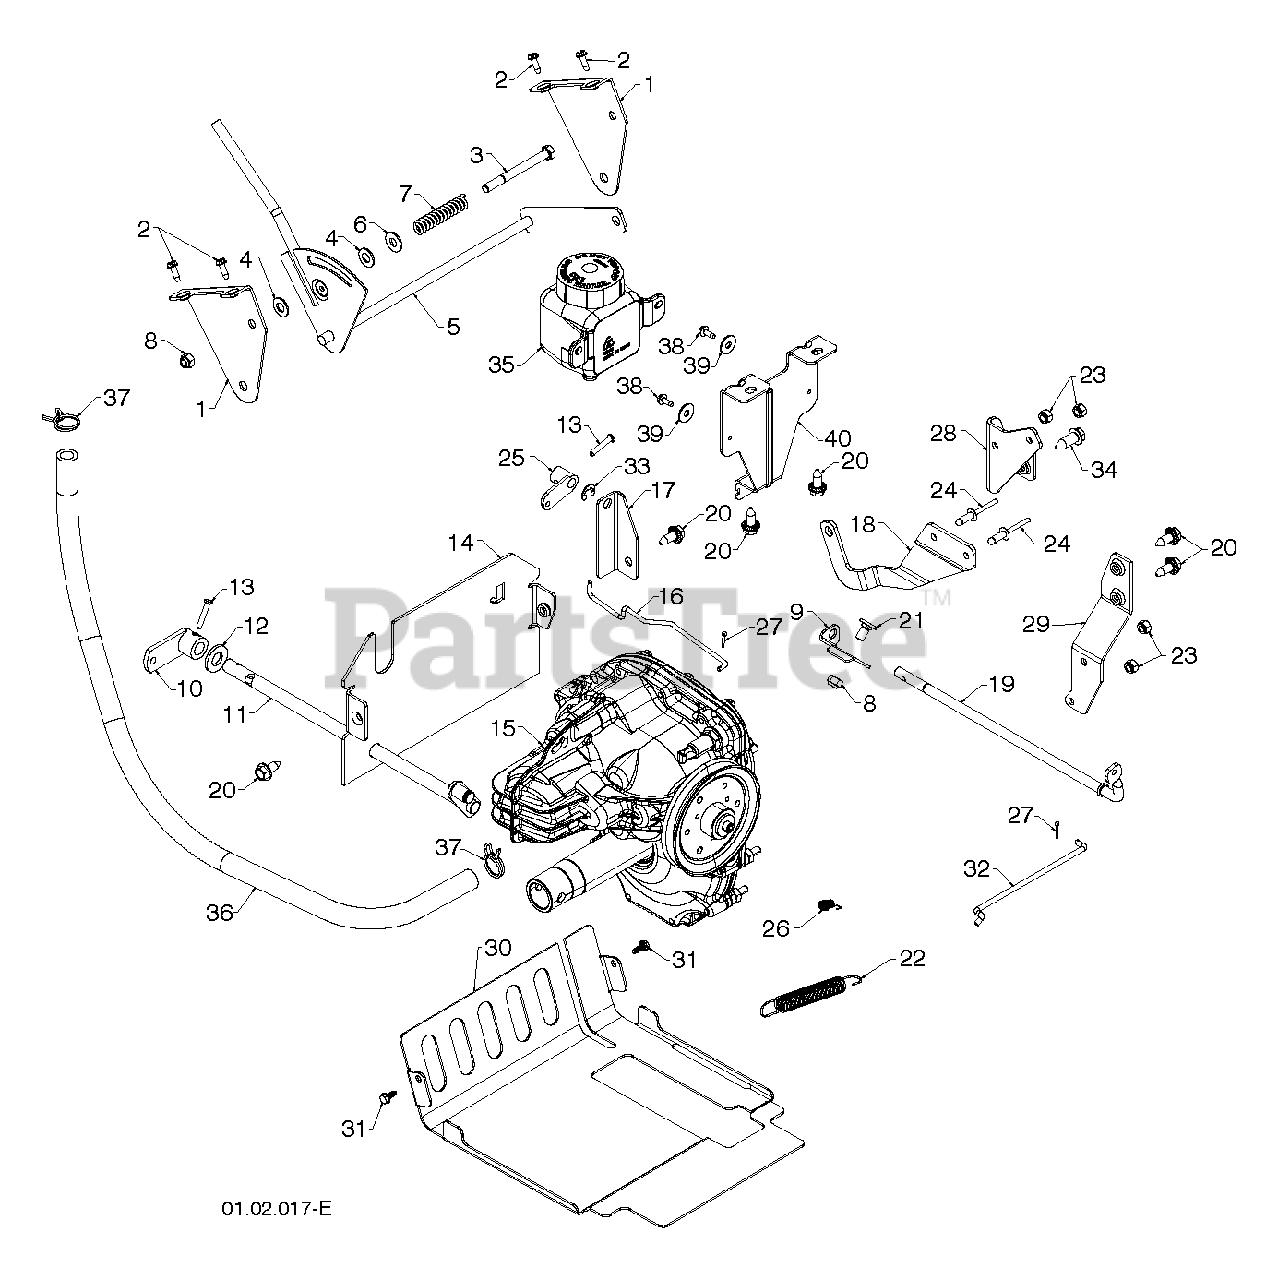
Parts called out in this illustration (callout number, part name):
1	BRACKET.SHIFT.HYDRO
2	SCREW #10-24 X 5/8
4	WASHER, NYLON FRICTION
5	LEVER ASSEMBLY, SPEED CONTROL
6	WASHER.20X8.5
7	SRPING.FRICTION.HYDRO
8	NUT.71038.31-18.HEX.NYLOCK
9	BRACKET.HYD.CLUTCH.
10	ARM.CONTRL.PIN.TRACK
11	CONTROL.SHAFT.ASM
12	WASHER.FLAT.1/2
13	CLEVIS PIN
14	PLATE.REAR.HYDRO.TRACK.ORANGE
15	TRANSMISSION
16	ROD, BYPASS VALVE
17	Clutch Bracket, Rear
18	ARM.CONTROL.HYDRO.SNOW
19	SHAFT.HYD.CLUTCH
20	BOLT.HEX.HD.WASHER.5/16-18X.75
21	BOLT.CARRIAGE.5/16-18X
22	SPRING, BRAKE
23	LOCKNUT.NYLOC.1/4-20
24	RIVET.POP.1/4X.475
25	ARM.HYD.CLUTCH
26	SPRING, TRACTION IDLER
27	RETAINER CLIP
28	BRACKET, ANTI-ROTATE
29	STRAP.TORQUE.HYDRO
30	COVER.TRANSMISSION.TRACK.BLACK
31	SCREW1032X.500
32	ROD.HYDRO CLUTCH
33	E-RING.RETAINER.REINFORCED.375
34	SCREW 5/16-18X1
35	TANK.EXPANSION.350ML 71328
36	HOSE.EXPANSION.TANK.TRACK
37	CLAMP.SPRING.HOSE.795
38	SCREW.HEX.WASH.HD.TAPPING
39	BRACKET.EXPANS.TANK.TRACK.GREY
